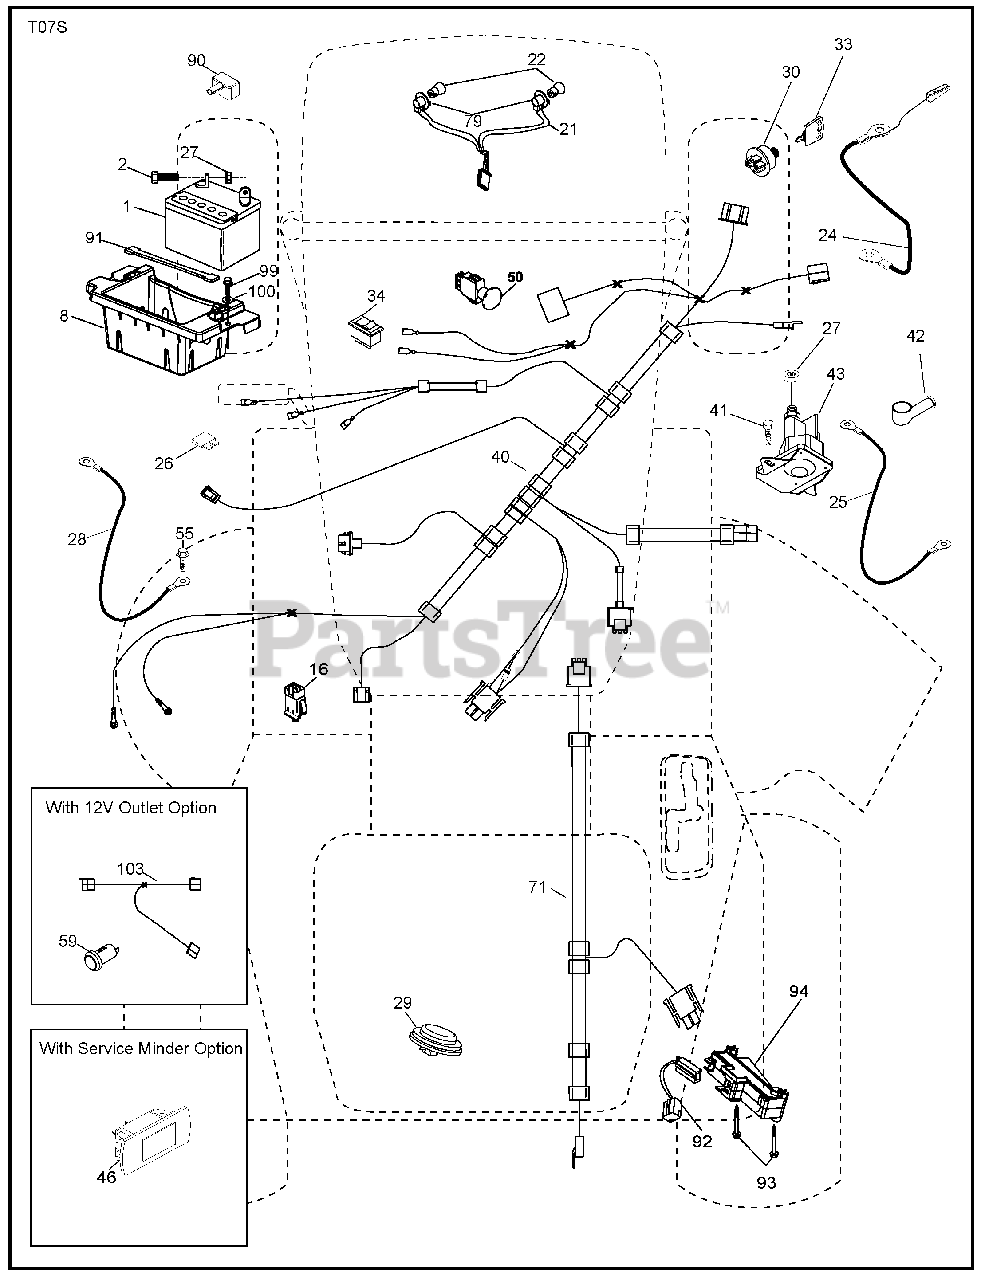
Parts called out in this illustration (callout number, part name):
1	BATTERY.DRY.30.AMP
2	Bolt Hex Hd 1/4-20 unc x 3/4
8	Battery Box
16	Switch Interlock
21	Harness Socket Light
22	Bulb, Light #1156
24	Cable Battery
25	Cable Starter
27	Nut Keps Hex 1/4-20 unc
28	Cable Ground 21" Blk 6 Ga.
29	Switch Seat
30	Switch Ign
33	Key/Chain
34	Switch Light/Reset
40	Harness Ign. Dash
41	Screw Thd Cut 1/4-20 x 1/2
42	Cover Terminal Red
43	Solenoid
46	Gauge Hourmeter
50	Switch PTO
55	Screw Thdrol 5/16-18 x 3/4
59	Outlet 12-Volt
71	Harness Ign Chassis
79	Socket Asm Bulb
90	Cover Terminal Battery
91	Strap Battery
92	Harness Pigtail Reverse Switch
93	Screw Plastite 10-14 X 2.00
94	Module Reverse ROS
99	Screw Hexwsh Thdrol 1/4-20 x 3/4
100	Washer 9/32 x 7/8 x 16 Ga.
103	Harness Pigtail 12 V Outlet
